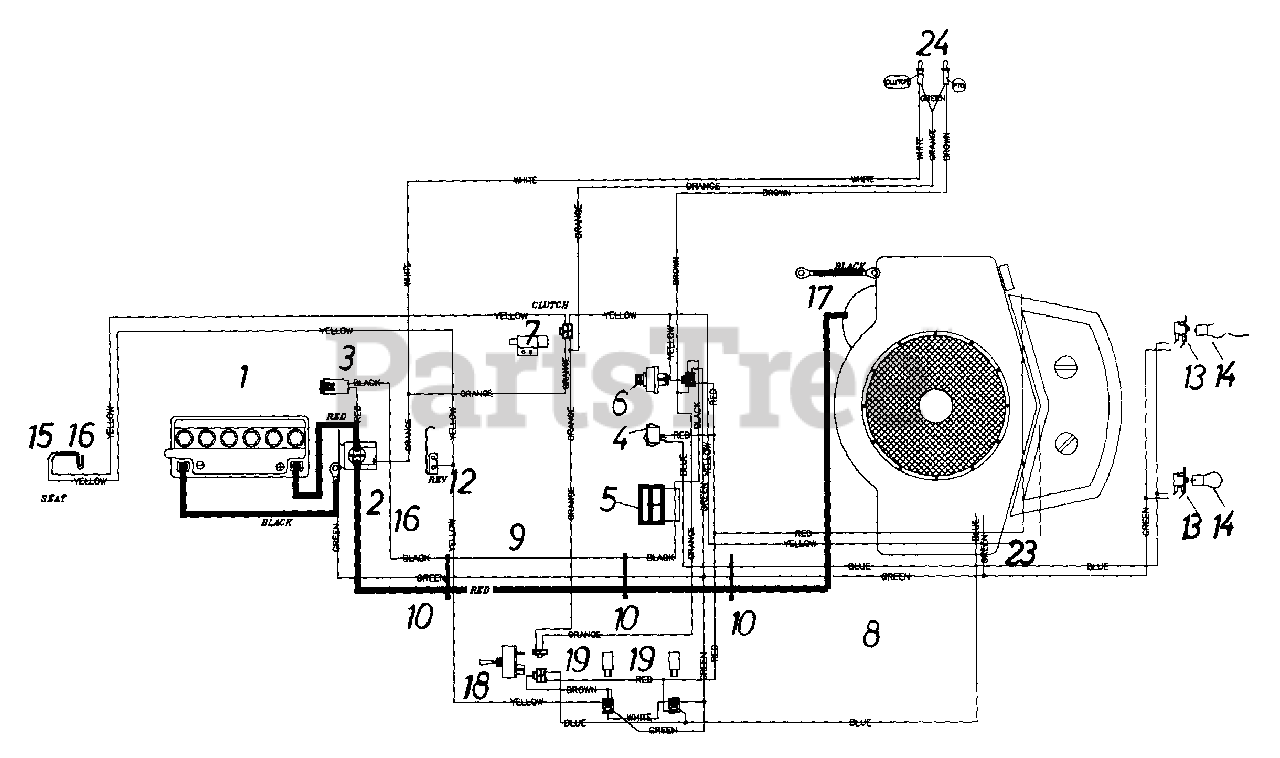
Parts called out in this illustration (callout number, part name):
1	Battery
2	Solenoid
3	Fuse
4	Light Switch
5	Ammeter
6	Ignition Switch
7	Clutch Safety Switch
8	Electric Wire
9	Wire Harness
10	Cable Tie
12	Reverse Safety Switch
13	Headlight Socket
14	Bulb
15	Seat Safety Switch
16	Seat Safety Switch
17	Electric Wire
18	Safety Switch (PTO)
19	Relay
23	Electric Clutch
24	Bulb
